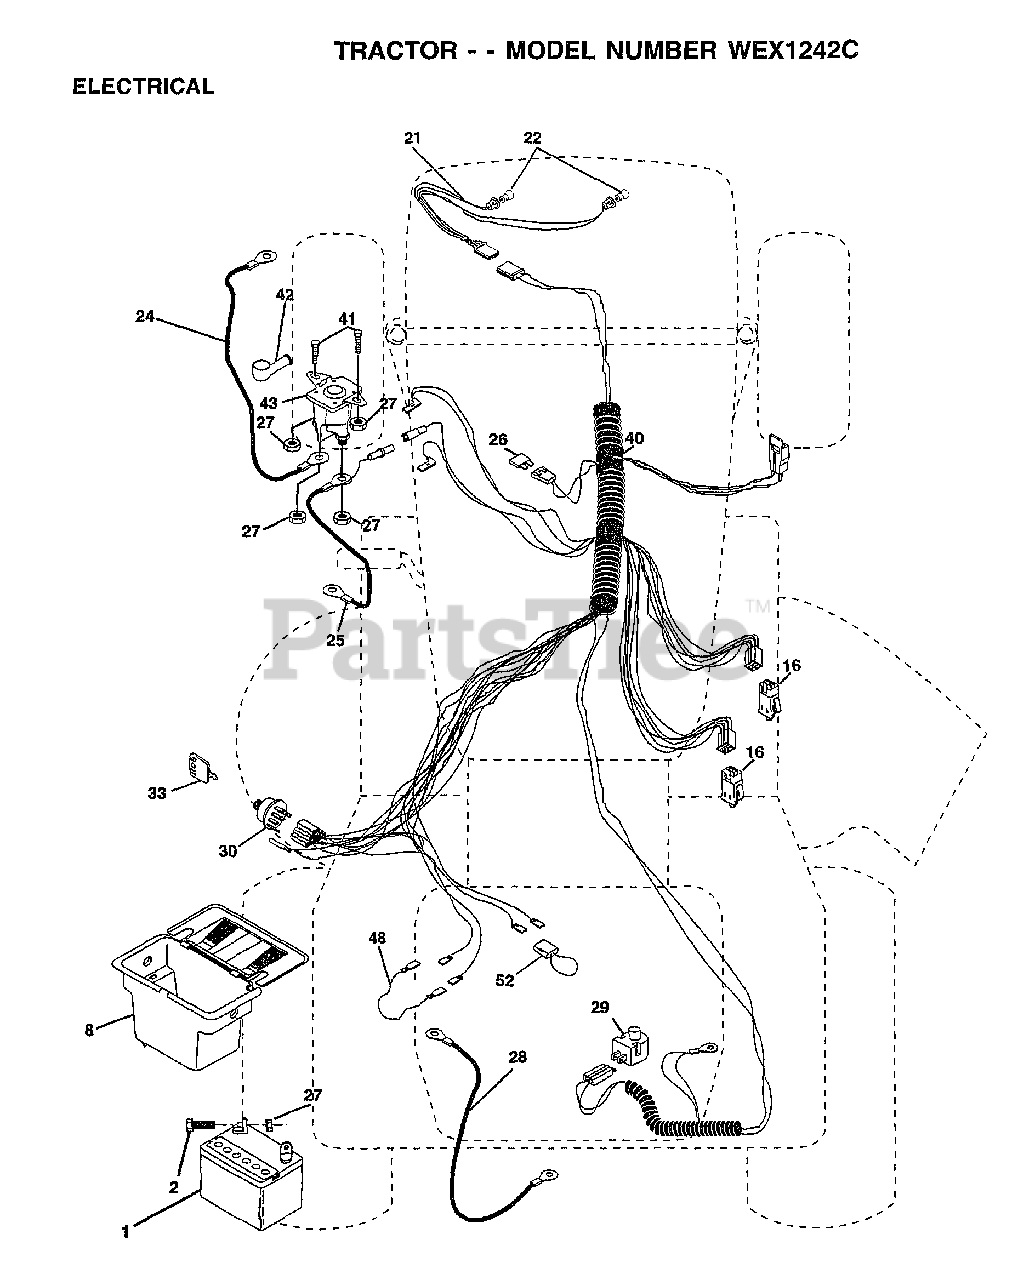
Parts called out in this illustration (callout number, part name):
2	BOLT LT
8	"CASE,BATTERY.MECH"
16	SWITCH INTERLOCK
21	HARNESS.ASM.LIGHT W/4152J
22	HEADLAMP BULB
24	"CABLE T, BATTERY"
25	CABLE.BTRY.6GA.RD
26	FUSE.15 AMP
27	NUT
28	CABLE T
29	SWITCH SEAT
30	SWITCH.IGN.
33	KEY MLD GEN DELTA
40	HARNESS IGN
41	BOLT HXHD FIN
48	ADAPTER AMMETER
52	PROTECTION LOOP
